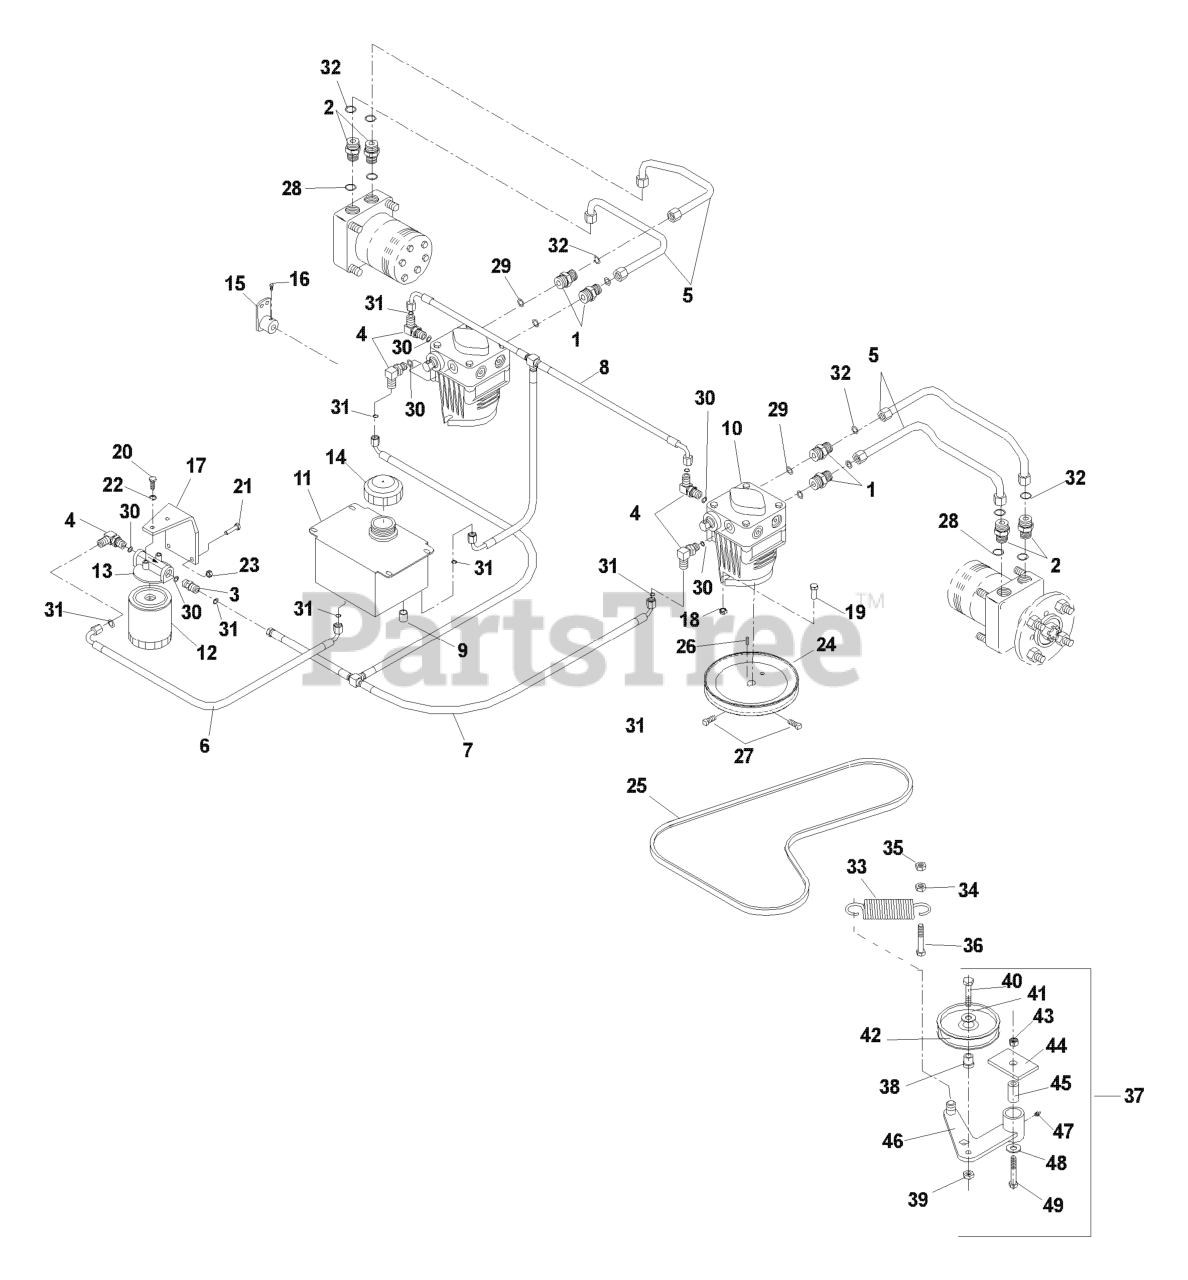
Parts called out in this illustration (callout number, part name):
1	FITTING, STRAIGHT F6400-8-8-0
3	STRAIGHT FITG
4	ELBOW, F6801-6-6-0 90 DEGREE
5	HYDRAULIC HOSE
7	TEE ASSEMBLY
8	TEE ASSEMBLY
9	NUT 9/16-18 JIC CAP
10	HG_PUMP
12	HYDRAULIC OIL FILTER
13	FILTER HEAD
14	HYDRAULIC CAP
15	PUMP LEVER
16	5/16C X 5/8 "V" POINT
17	OIL FILTER BRKT
18	NUT 3/8C CENTERBLOCK
19	4CS 3/8C X 1 SERRATED HEAD
20	HCS 1/4C X 5/8
21	HCS 1/4C X 3/4 HCS
22	LOCKWASHER 1/4"
23	NUT.1/4-20.HEX.NYLOC.ZD
25	PUMP BELT
26	KEY 5 MM SQ X 25 MM
27	SCREW 5/16C X 5/8 SQ HEAD
34	NUT 3/8C WHIZ
35	NUT 3/8-16 NYLOC
36	HCS 3/8C X 2
37	TORSION SPRING
38	BUSHING, IDLER FLANGE
39	NUT 3/8C CENTERBLOCK
40	HCS 3/8-16 X 1 3/4 GR5
41	WASHER 3/8 FLAT
42	IDLER PULLEY
43	NUT 1/2-13 HEX NYLOC ZD
45	PIVOT BUSHING
46	IDLER ARM WLDT
47	ZERK
48	WASHER 1/2 FLAT
49	HCS 1/2C X 3 1/4
